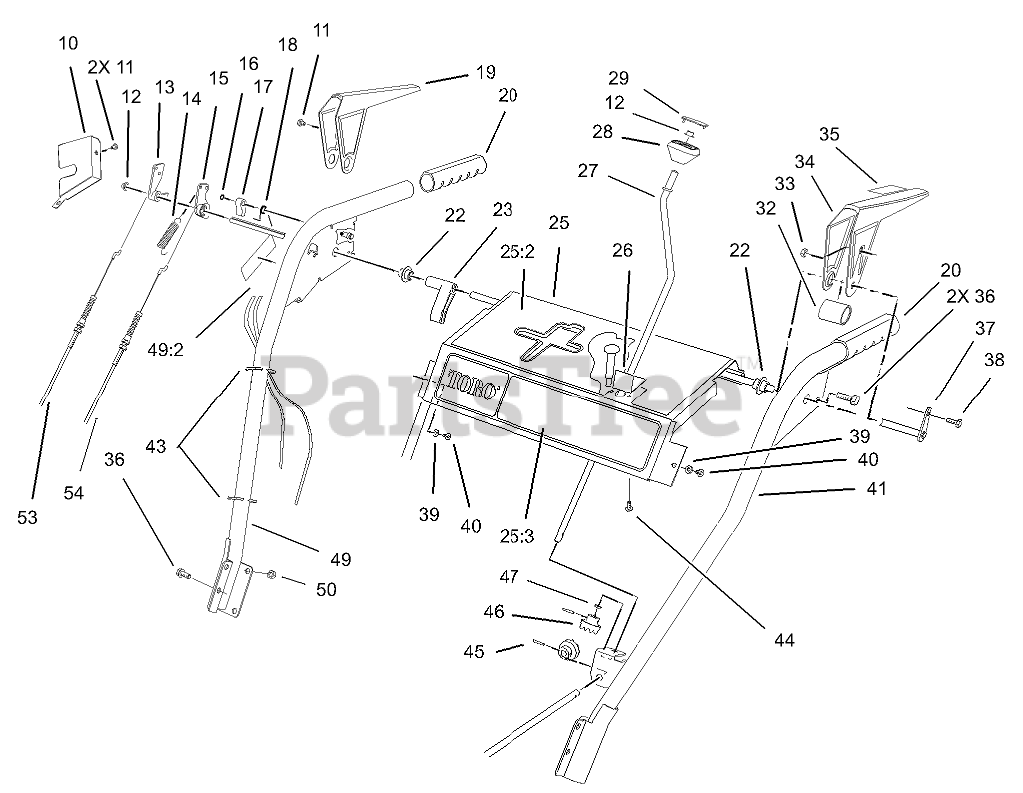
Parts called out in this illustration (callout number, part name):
10	COVER-LOCK, LEVER
11	SCREW-HH
12	RETAINER-PUSH ON
13	TANG-LOCKING
14	SPRING-EXTENSION
15	CAM-RELEASE
16	E-RING-RETAINER
17	LATCH-LOCKING
18	SPRING-TORSION
19	LEVER-TRACTION, RH
20	GRIP-HANDLE
22	BUSHING-LEVER
23	LEVER-TRIP
25	CONTROL PANEL ASM
25:2	DECAL-PANEL, TOP
25:3	DECAL - FRONT PANEL
26	PLATE-GUIDE
27	CRANK-ROD, CHUTE
28	KNOB-CONTROL, CHUTE
29	COVER-KNOB
32	SPACER-LEVER, TRACTION
33	NUT-LOCK, NI
34	LEVER-TRACTION, LH
35	DECAL-LEVER
36	SCREW-HWHTF
37	CROSS ROD ASM
38	SCREW-HWH
39	WASHER-FLAT
40	SCREW-HWHTF
41	LH HANDLE ASM
43	TIE-CABLE
44	SCREW
45	PIN-SPRING
46	GEAR-UNIVERSAL
47	WASHER-RUBBER
49	HANDLE ASM
49:2	DECAL-WARNING
50	NUT-LOCK, NI
53	CABLE-IMPELLER
54	CABLE-TRACTION
